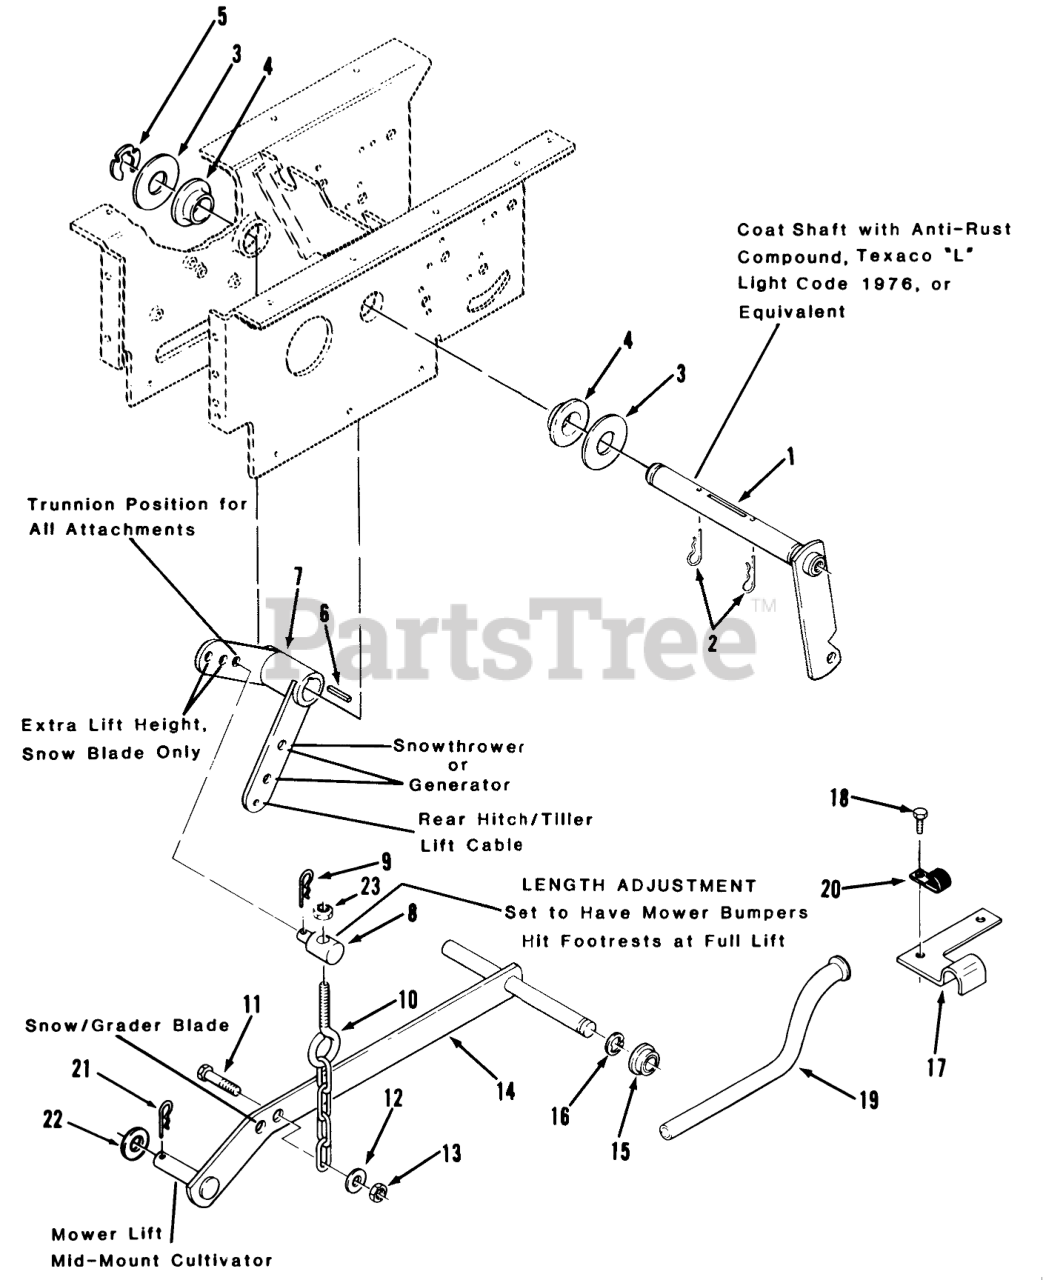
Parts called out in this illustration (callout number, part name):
1	WLDMT-LIFT ARM
2	Pin-Cotter
3	WASHER
4	BEARING-FLANGE
5	Retainer
6	KEY-SQUARE
7	Bellcrank
8	TRUNNION-LIFT
9	Hairpin Cotter
10	CHAIN-LIFT
11	Bolt
12	WASHER 5/16 SAE
13	Nut
14	ASSY LIFT BAR R
15	BUSHING
16	E Ring
17	CLAMP-CONDUIT R
18	BOLT
19	TUBE-CONDUIT R
20	CLIP
21	Hairpin Cotter
22	Washer
23	NUT
